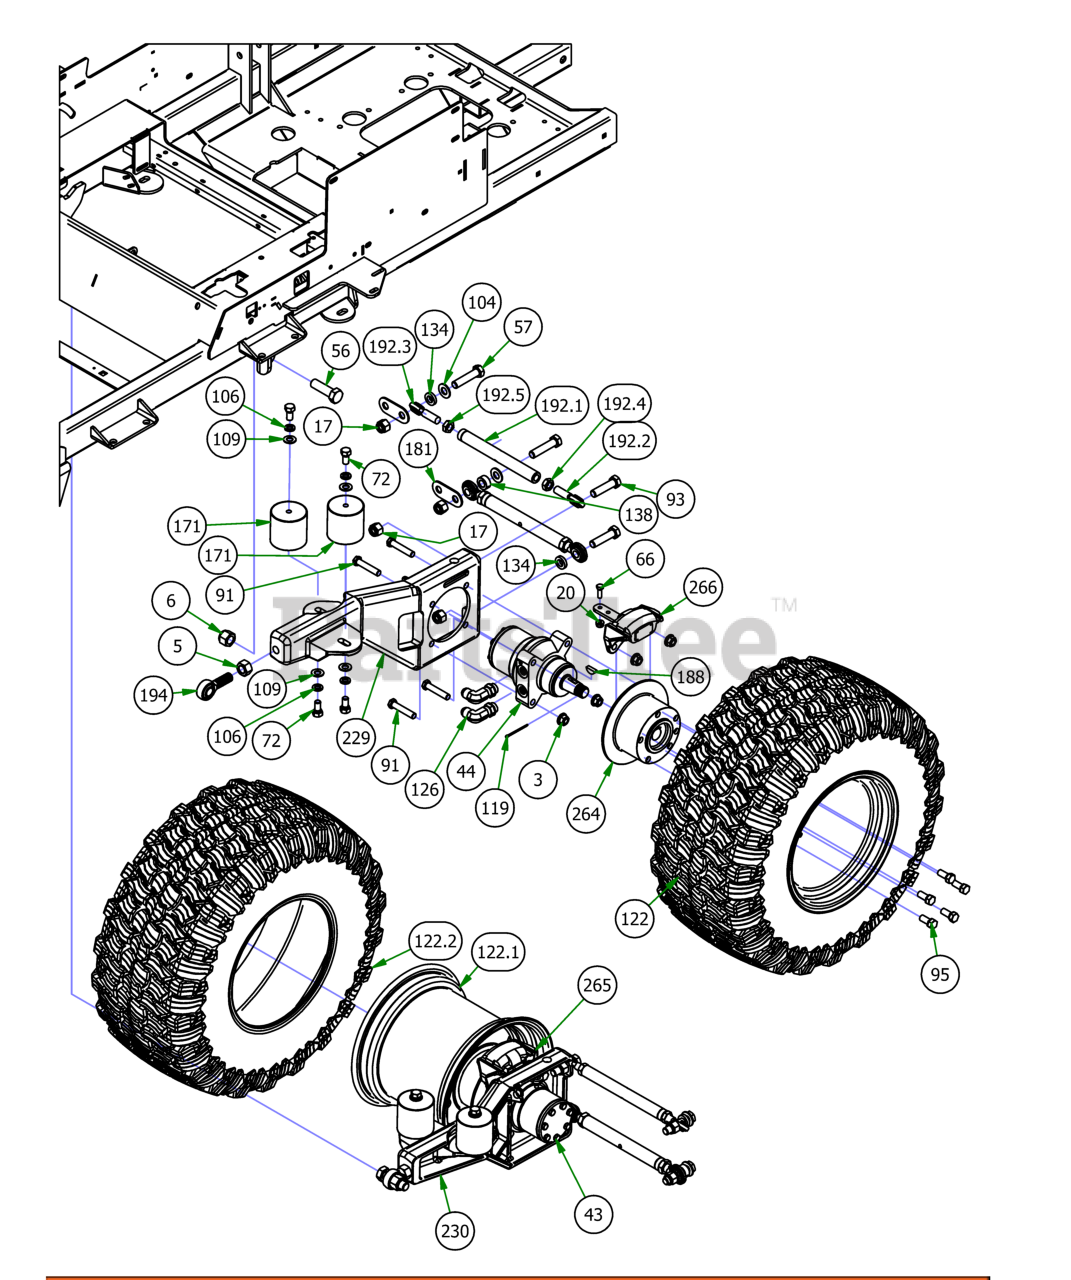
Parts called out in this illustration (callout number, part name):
3	1/2-13 Gr 8 Centerlock Flange Nut
5	3/4"-16 Fine Full Nut
6	3/4" Course Thread Nylon Lock Nut
17	5/8 Std NC Nylock Nut
20	5/16-18 Nylon Flange Nut
43	18cc Parker Wheel Motor- Right
44	18cc Parker Wheel Motor- Left
56	3/4 x 2 1/2 Course Thread Bolt
57	AS 2465 - 5/8 x 2 3/4 UNC
66	5/16" x 1" Bolt
72	1/2" x 1" Hex Bolt
91	1/2-13 x 2.75 Gr. 8 Hex Head Bolt
93	5/8" x 2 1/2" Grade 5 Hex Bolt (Coarse)
95	1/2-20 x 1-1/2 Lug Bolts Zinc
104	5/8" Flat Washer SAE Spec Grade 8
106	1/2" Lock Washer
109	1/2" Washer (Grade 8)
119	1/8x2-1/4 cotter pin Zinc
122	2019 Assy-26x12-12 Reaper Turf -10.5" Rim
122.1	2019 10.5" Wheel
122.2	2019 26x12-12 Reaper Turf Tire
126	2019 Rouge/Renegade Wheel Motor 90* Fitting #6801-10L
134	Spacer 1.125OD x .625 ID x .250 Length
138	5/8" x 1/" Collar W/One Set Screw
171	Vibration Mount-Blue Dot
181	2019 Suspension Gusset Outlaw
188	Woodruff Key
192	2019 Suspension Radius Rod Assembly
192.1	2019 Suspension Link Body
192.2	2019 RH 5/8" Heim
192.3	2019 LH 5/8" Heim
192.4	5/8-11 HEX JAM NUT ZINC
192.5	NUT, 5/8-18LH
193	2019 Suspension Radius Rod Assembly
193.1	Rear Radius Rod, 3/4 Body
193.2	3/4-16 x 5/8 RH Heim
193.3	3/4-16 x 5/8 LH Heim
193.4	3/4-16 HEX JAM NUT ZINC
193.5	3/4-16 LH HEX JAM NUT ZINC
194	3/4-16 RH Male Rod End
229	2019 Left Trailing Arm
230	2019 Right Trailing Arm
233	2019 Renegade Diesel Frame - Powdercoated
264	Brake Disk
265	XP/AOS Right Brake Caliper
266	XP/AOS Left Brake Caliper
